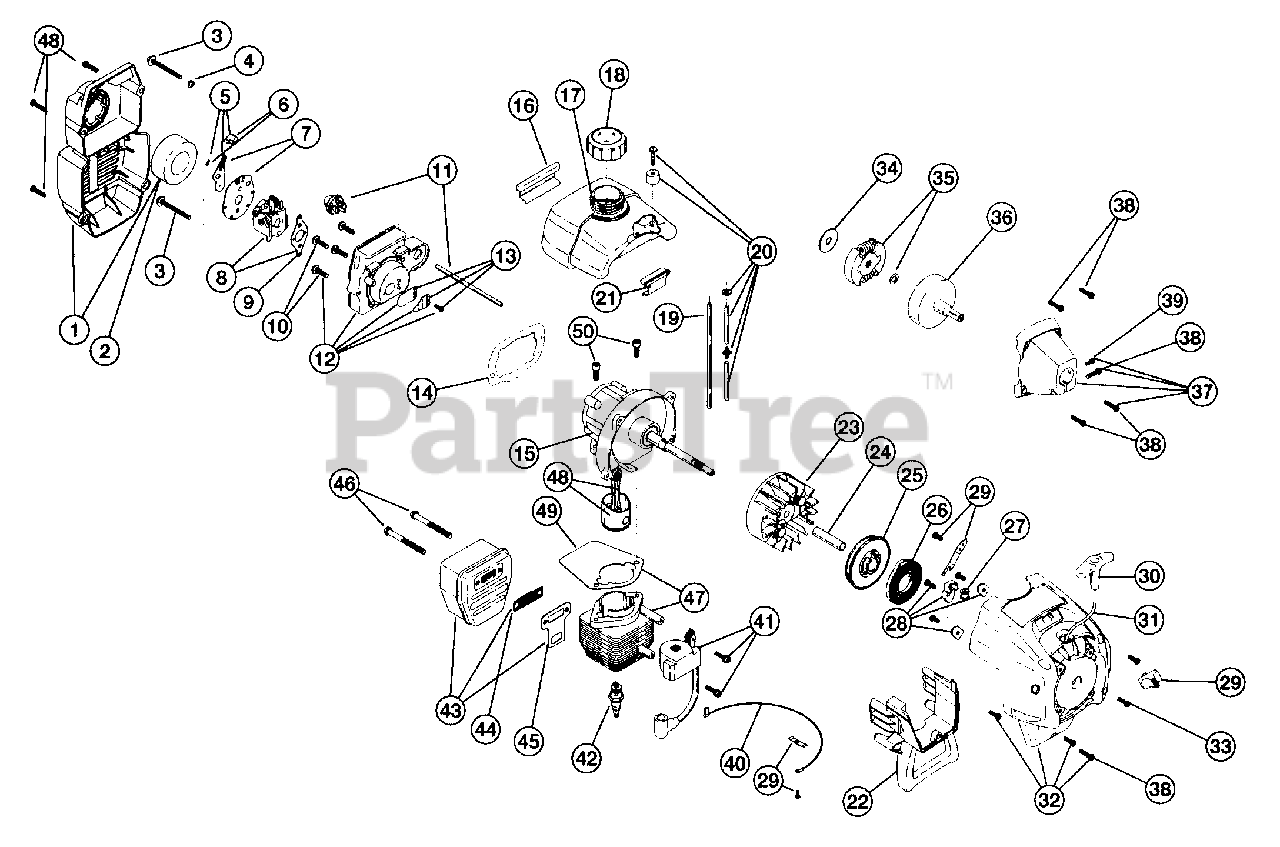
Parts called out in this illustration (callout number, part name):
1	Air Cleaner/Muffler Cover Assembly
2	Air Cleaner Filter
3	Carburetor Mounting Screw Assembly
4	Wavey Washer
5	Choke Lever Assembly
6	Choke Knob and Screw
7	Choke Lever and Plate
8	Carburetor Assembly
9	Carburetor Gasket
10	Carb Mount Screw
11	Primer and Hose Assembly
12	Carb Mount Assembly
13	Reed Assembly
14	Carburetor Mount Gasket
15	Crank Case Service Assembly
16	Rear Mounting Pad
17	Fuel Tank Assembly
18	Fuel Cap Assembly
19	Fuel Return Line
20	Fuel Line Assembly
21	Front Mounting Pad
22	Shroud Extension and Stand
23	Flywheel Assembly
25	Recoil Pulley Assembly
26	Recoil Spring
27	Rope Guide
28	Pulley Retainer Assembly
29	Switch Assembly
30	Pull Handle
32	Starter Housing Assembly
33	Housing Screw
34	Clutch Washer
35	Clutch Rotor Assembly
36	Clutch Drum Assembly
37	Clutch Cover Assembly
39	Anti-Rotation Screw
40	Wire Lead
41	Module Assembly
42	Spark Plug
43	Muffler Assembly
44	Spark Arrestor Screen
45	Exhaust Gasket
46	Muffler Mounting Bolt Assembly
47	Cylinder Assembly
48	Piston and Rod Assembly
49	Cylinder Gasket
50	Cylinder Bolt
